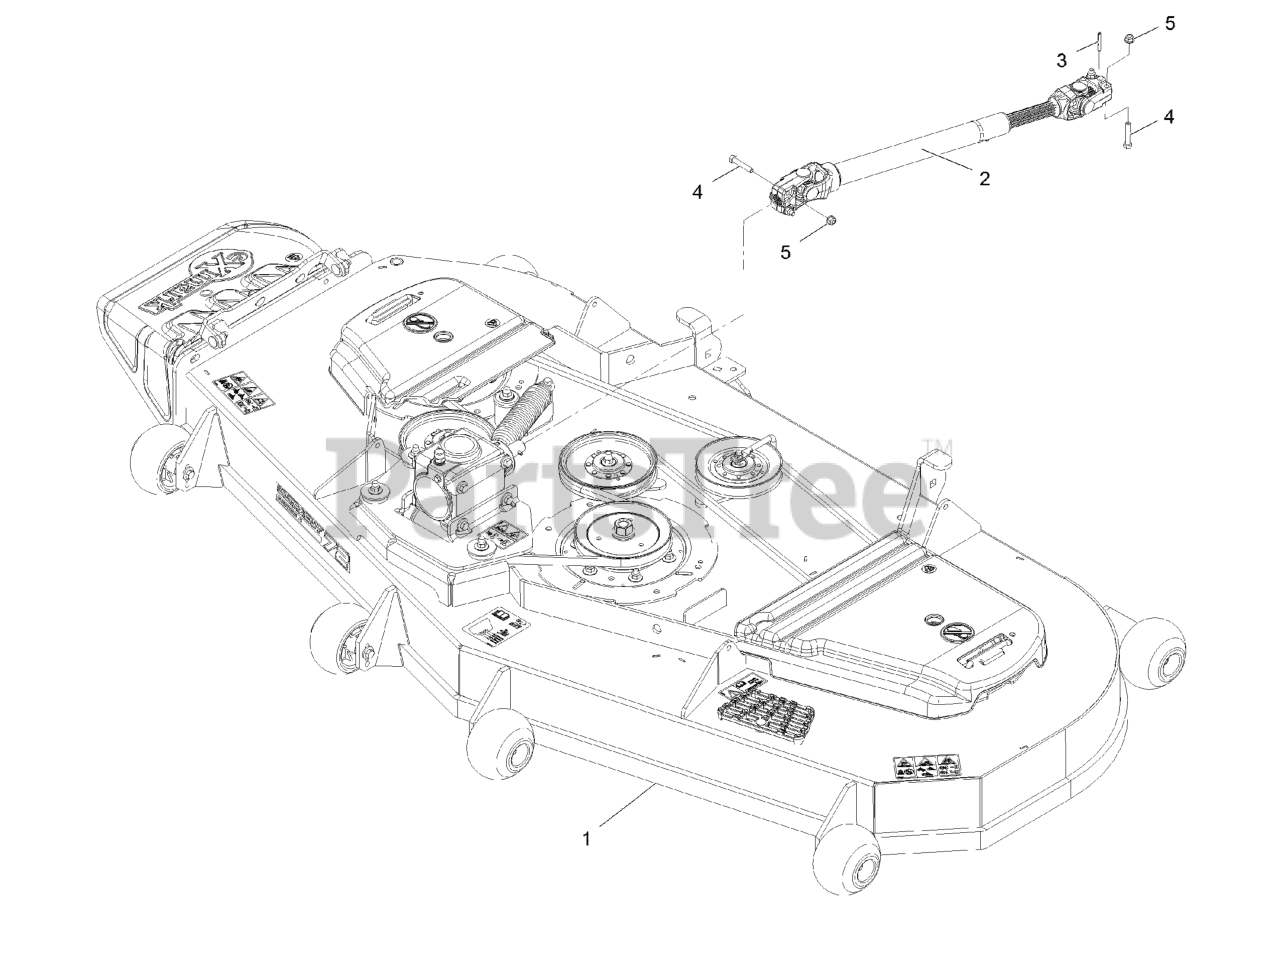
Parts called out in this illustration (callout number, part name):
1	Deck ASM-724
2	DRIVESHAFT ASM
3	PIN-ROLL
4	SCREW-HH
5	NUT-HF, NI
